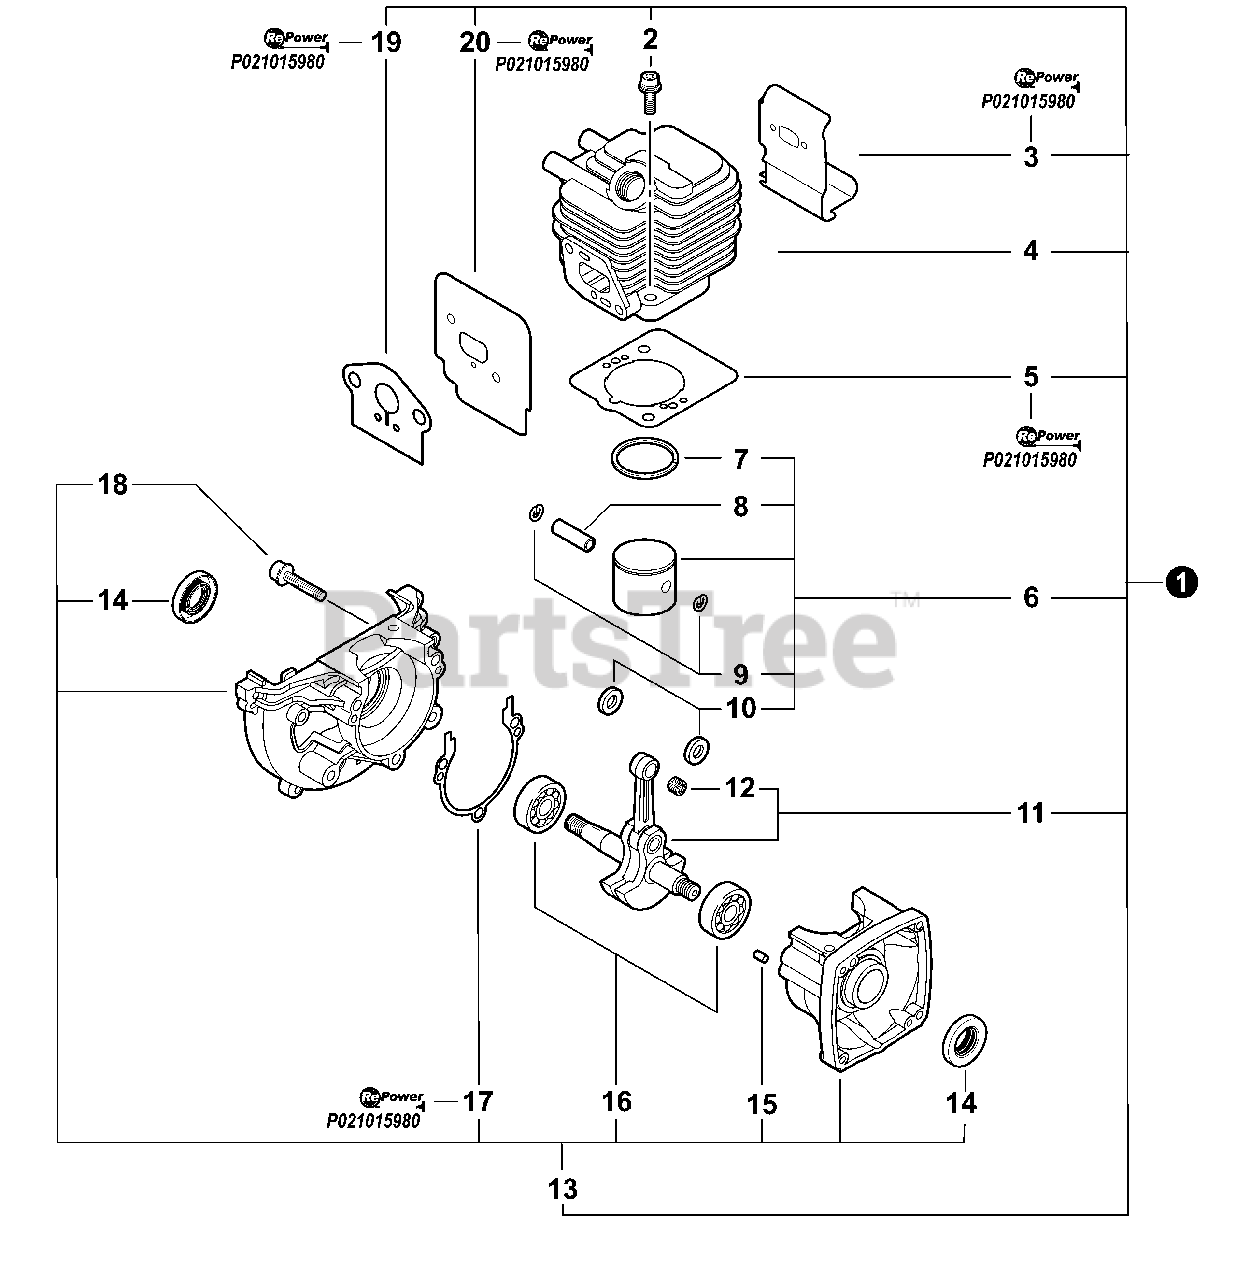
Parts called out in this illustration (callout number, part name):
1	SHORT BLOCK -- SB1096
2	SCREW - 5×22
3	SHIELD, EXHAUST
4	CYLINDER
5	GASKET, CYLINDER
6	PISTON KIT
7	RING, PISTON
8	PIN, PISTON
9	RING, RETAINING
10	SPACER, PISTON
11	CRANKSHAFT ASSY
12	BEARING, NEEDLE - 8
13	CRANKCASE KIT
14	SEAL, OIL
15	PIN, LOCATING - 4×8
16	BEARING, BALL - 6201
17	GASKET, CRANKCASE
18	SCREW - 5×28
19	GASKET, INTAKE
20	SHIELD, INTAKE
